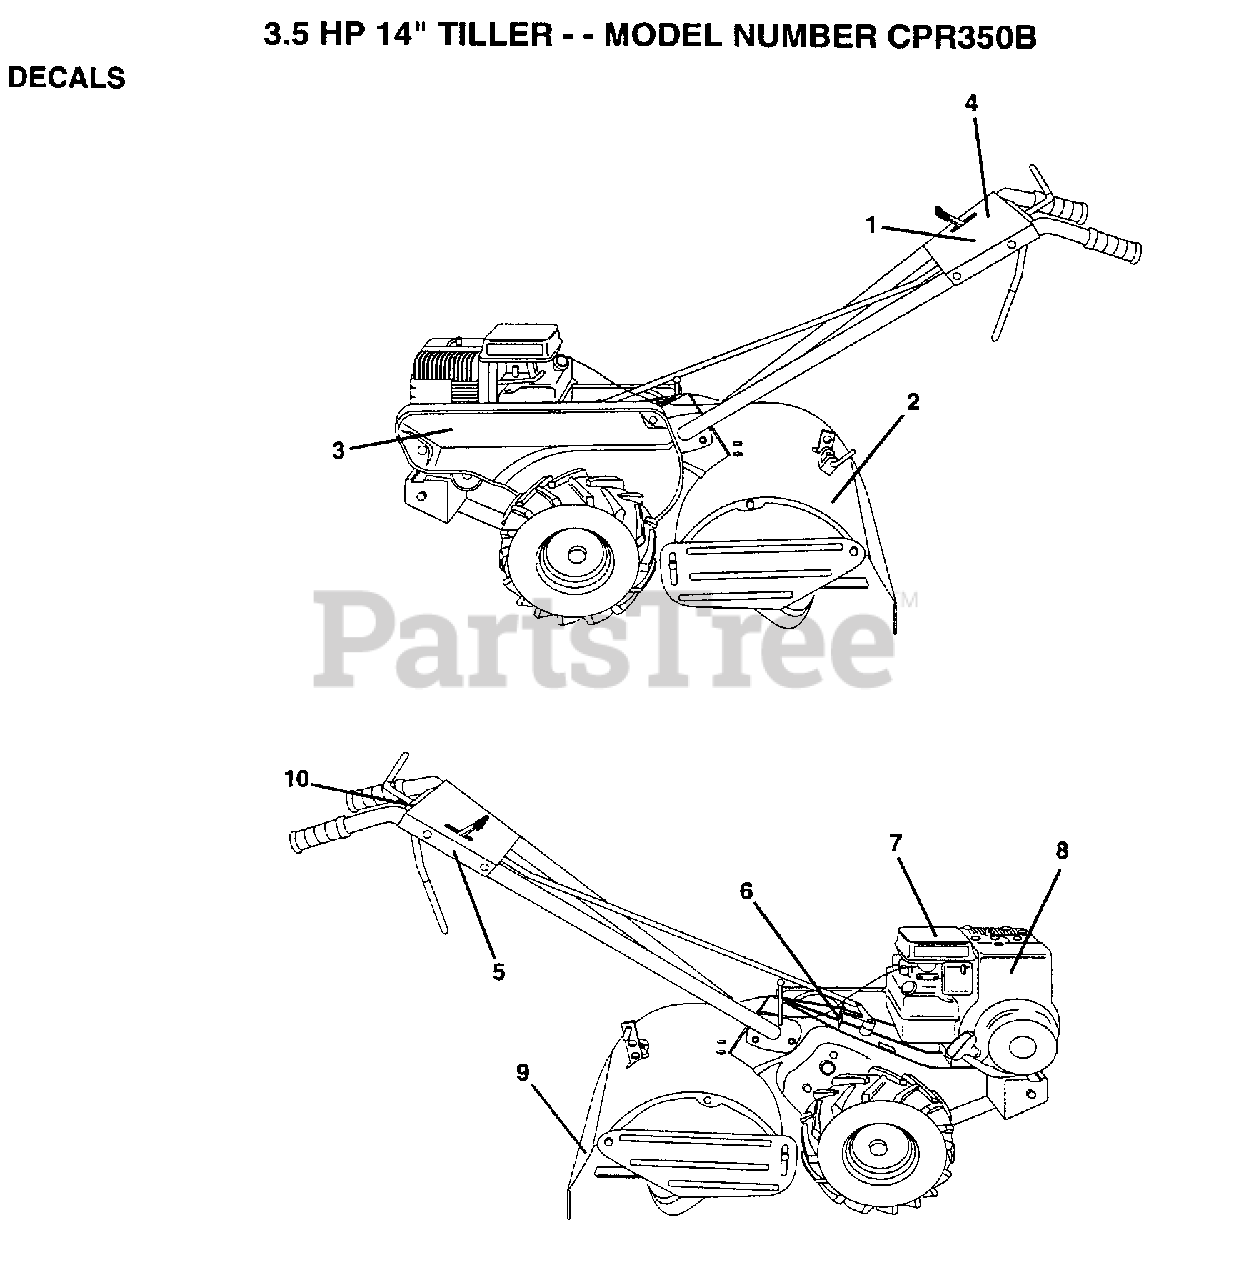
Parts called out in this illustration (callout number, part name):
1	DECAL.PNL.CNTL.
2	DECAL, LOGO
3	DECAL.GUARD.BELT
4	DECAL, PANEL CONTROL
5	DECAL TI
6	DECAL CRT
8	"DECAL,ENG HP"
9	DECAL TI
